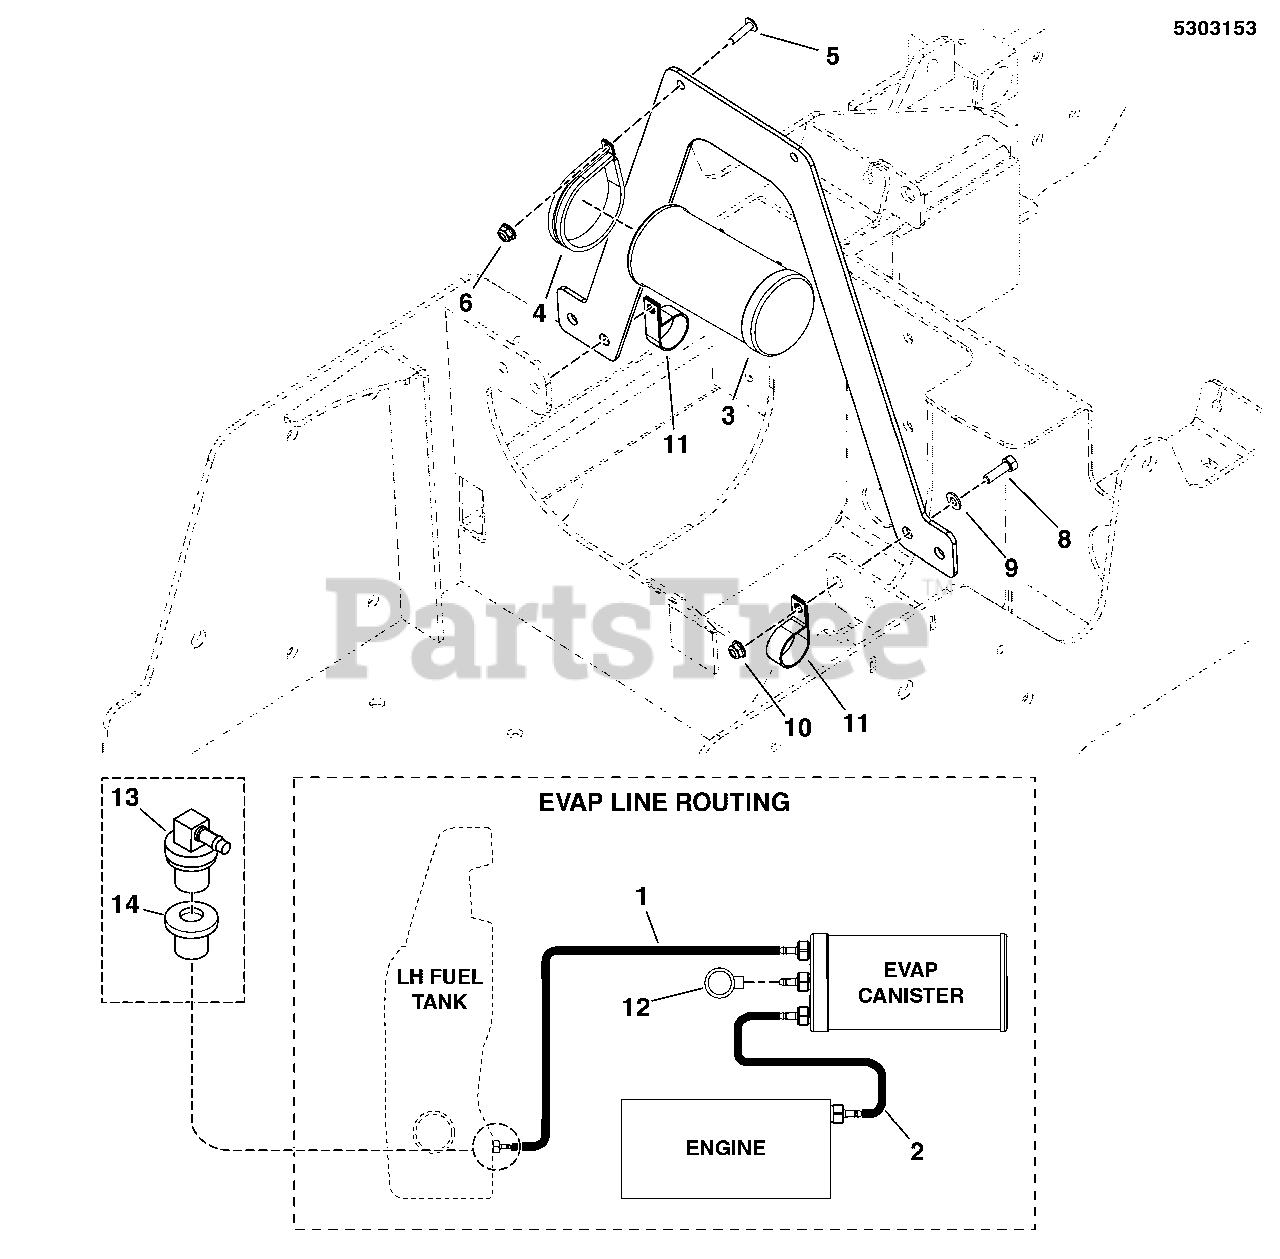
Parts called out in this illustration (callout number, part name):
1	HOSE, VAPOR, 5MM ID, 23.00 LG
2	HOSE, VAPOR, 5MM ID, 33.50 LG
3	CNSTR, CARB, 6 GAL
4	CLAMP, 3" ID, CUSHIONED, STAINLESS
5	SCREW, 1/4-20 X 3/4 ALLEN BH
6	NUT, 1/4-20 HEX NYLOCK FLANGE (5025391)
7	PLATE, MOUNT, CANISTER, IS600 - BLK
8	BOLT, 5/16-18 X 1" GD
9	WASHER, 5/16
10	NUT, 5/16-18 HEX NYLOCK FLANGE
11	CLAMP, TUBE & WIRING, 1.062 ID
12	DUST FILTER, CANISTER
13	ASSEMBLY, REMOTE VENT - NO VALVE
14	GROMMET
